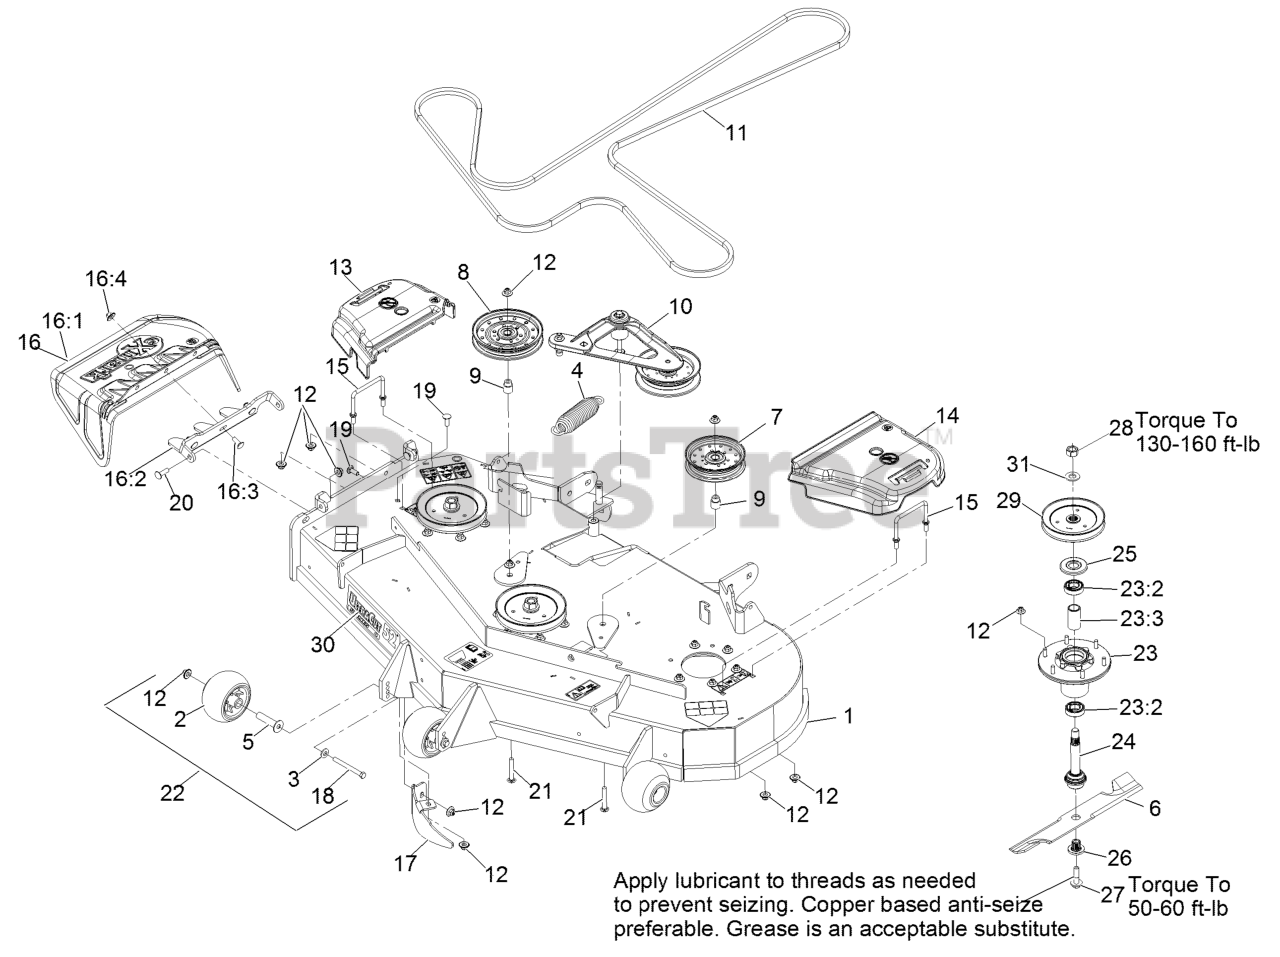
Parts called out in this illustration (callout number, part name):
1	ASM,DECK W/ DECALS 52
2	ROLLER-SCALP, ANTI
3	WASHER-BELLEVILLE
4	SPRING-EXTENSION
5	AXLE, ROLLER
9	BUSHING-IDLER
10	DECK IDLER ASM
11	BELT,V-B X 186.00"
12	Nut-Nyloc 3/8-16 Flg
13	COVER-BELT, RH
14	COVER-BELT, LH
15	WIREFORM-COVER
16	ASM,DISCHARGE CHUTE
16:1	CHUTE,DISCHARGE
16:2	BRACKET,DISCHARGE CHUTE
16:3	SCREW-CARR
16:4	Nut-Nyloc 3/8-16 Flg
17	BAFFLE-DOGLEG, LZ-VT52
18	SCREW-HH 3/8-16 X 3 3/4 GR 8
19	SCREW-CARR
20	Bolt-Carriage 3/8-16 X 1 1/4
21	SCREW-CARR
22	KIT, ANTI-SCALP ROLLER
23	ASM-CUTTER HSG WITH BEARINGS
23:2	BEARING-BALL
23:3	SPACER-BEARING
24	ASM-SPINDLE AND SEAL
25	GUARD,BEARING TOP .989
26	BUSHING,SPLINED
27	SCREW,SEMS 1/2-20 X 2.19
28	NUT-HEX
29	SHEAVE,BLADE DRIVE 6.50
30	DECAL,ULTRACUT 52 SERIES
